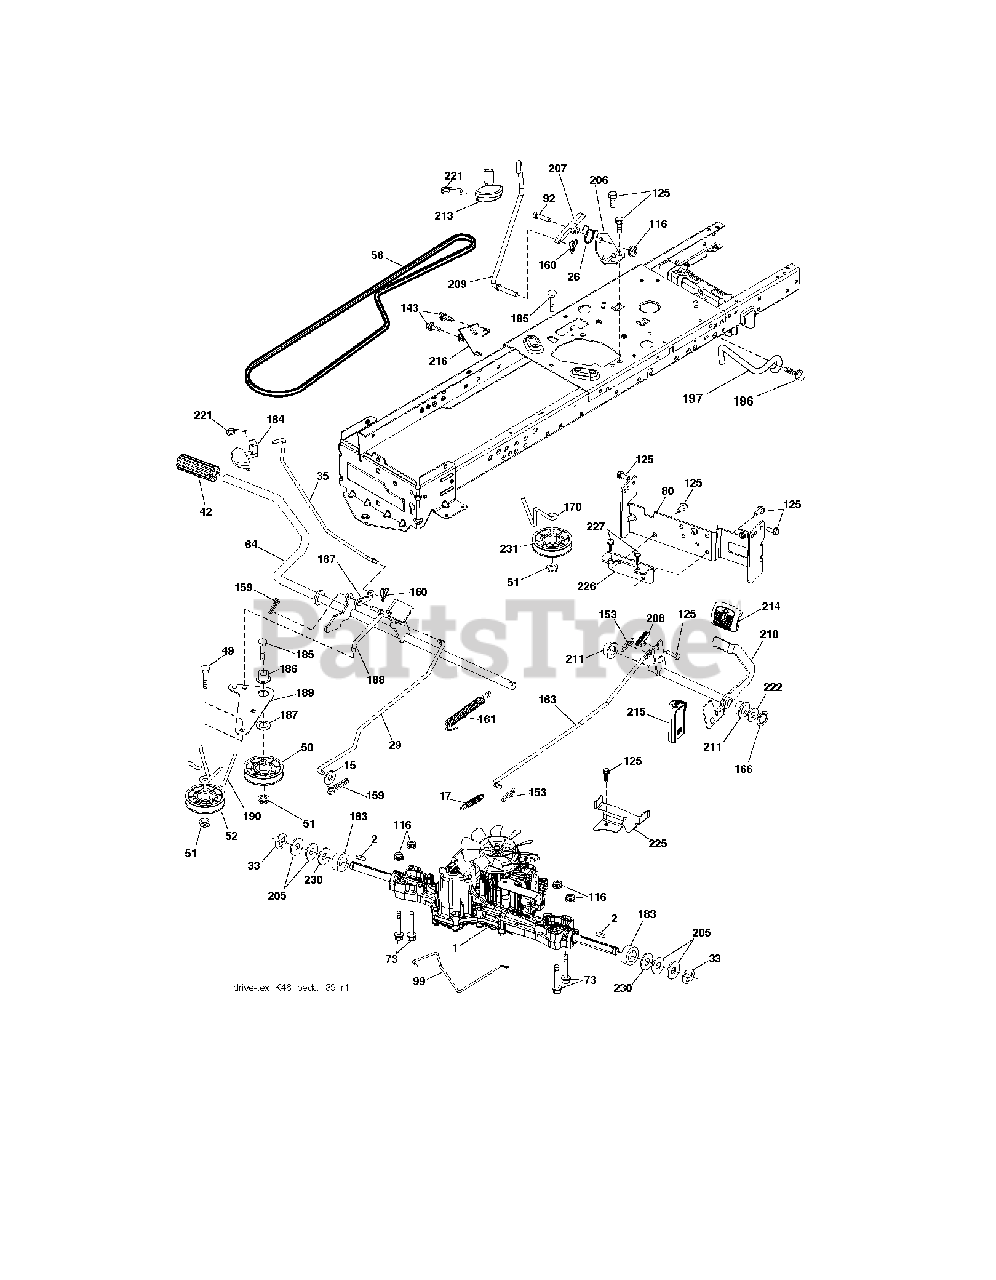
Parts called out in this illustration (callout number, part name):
2	SQUARE KEY
17	SPRING.BRAKE.K46.GREEN
26	SPRING.RETURN.CRUISE
29	ROD.BRAKE.K46
33	E-RING LT
35	ROD.BRAKE.PARKING.LT.T
49	BOLT
50	IDLER.FLAT.910.OFFSET
51	NUT LOCK FLG 3/8-16 UNC
52	IDLER.V-GROOVE.910.OFFSET
56	V-BELT.MOWER.92.40.42/K46
64	SHAFT.ASM.PEDAL.BRK.CNTR
73	BOLT
80	STRAP.TORQUE.K46.K57R.TT
92	BOLT
99	ROD.SPRING.BYPASS.K46.LT.Z
116	NUT LOCK HEX FLANGE 5/16-18
125	SCREW
143	SCREW LT
159	COTTER PIN
160	RETAINER CLIP
161	SPRING, RETURN LT
163	ROD.CONTROL.PEDAL.K46
166	NUT.PUSH.625
167	LATCH.BRAKE.SPRING
170	KEEPER.CENTER SPAN.1.688
183	SPACER AXLE
184	HANDLE.PARKING.BRAKE.LTTEX.667
186	SPACER.RETAINER
187	WASHER 12/32X2X10GA
188	LINK.CLUTCH.GROUND.DRIVE
189	BELLCRANK.GROUND.DRIVE.TEX.
190	KEEPER.BELLCRANK.DRIVE
196	SCREW 3/8-16X1
197	LINK.CLUTCH.ANIT-ROTAT
206	BRKT.MOUNT.LATCH.CRUIS
207	LATCH.CONTROL.CRUISE
208	GEAR.SECTOR.CONTROL.CR
210	ROCKER.ASM.PEDAL.CONTR
211	BEARING.NYLON
213	HANDLE.CONTROL.CRUISE.ELTE
214	PEDAL.FORWARD.PAD.TEX
215	PEDAL.REVERSE.TEX.GT.4
216	BRACKET.PULLEY.IDLER.W/TEX
221	RETAINER.SPRING.CLIP.H
222	WASHER 21/32 X 1-1/4 X 10 GA.
225	KEEPER.BELT.TRANSAXLE.K46
226	BRACKET.MOUNT.TORQUE.K46.TLT
227	Screw, Lt
230	WASHER.HARDENED
231	IDLER.V-GROOVE.1.688.OFFSET
